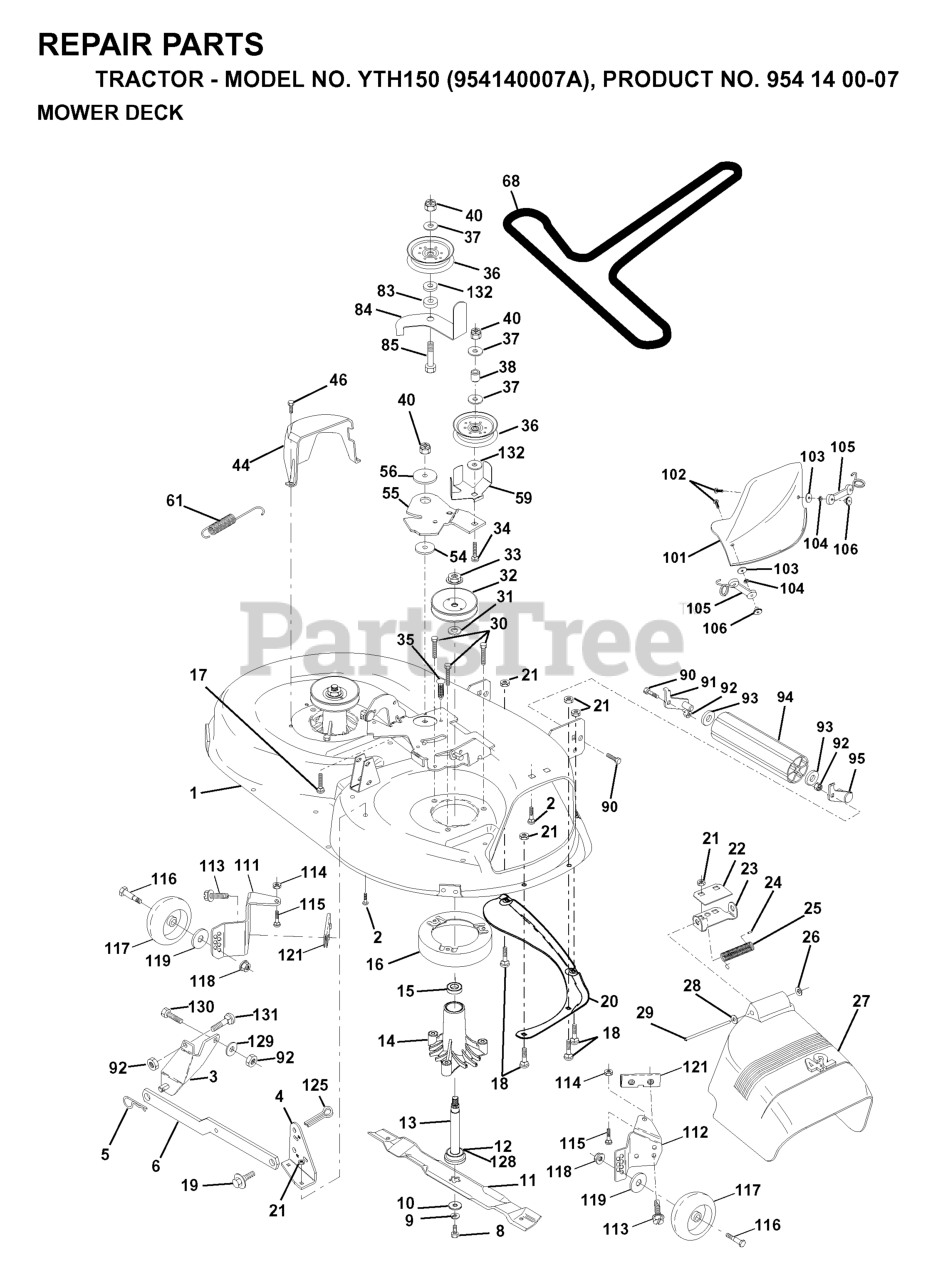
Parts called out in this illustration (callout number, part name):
1	DECK 42"
2	RP BOLT 5/16-18 X3/4 ZN/YEL GR
3	BRKT ASM SWAY BAR
4	BRKT DECK SW BAR
5	RETAINER-SPRNG RB
6	REAR SUSP ARM
8	BLADE BOLT
9	LOCKWASHER
10	WASHER.BLADE
11	BLADE.42".MULCH
12	BEARING.BALL.#6204.(MANDREL)
13	SHAFT ASM VENT
14	HOUSING.MANDREL.VENTED (MACHD)
16	STRIPPER
17	BOLT CARRIAGE
18	BOLT
19	BOLT SHD 5/16-18
20	BAFFLE
21	LOCKNUT
22	STIFFENER BRACKET
23	DEFLECTOR BRACKET
24	CAP-SLEEVE LT
25	SPRING TORSION
26	NUT PUSH M
27	SHIELD.DEFLECTOR.MOWER.42".BLK
28	Washer 11/32 x 5/8 x 16 Ga SD
29	ROD.HINGE
30	SCREW
31	WASHER
32	PULLEY/MANDREL
33	NUT
35	FASTENER.XMAS.TREE
36	FLAT IDLER PULLEY
37	WASHER
38	IDLER SPRING SPACER
44	GUARD MANDREL LH BLACK
46	SCREW.1/4-20X5/8
54	HARDENED WASHER
55	IDLER ARM
56	SPACER RETAINER
59	GUARD, BELT
61	SPRING EXTENSION
68	V-BELT TRIPATH
84	KEEPER.BELT.IDLER
85	BOLT
90	BOLT
91	BRACKET LH (A)
92	NUT
93	Washer 1 17/32 X 7/8 X 16 Ga
94	NOSE ROLLER
95	BRACKET RH (B)
101	COVER MULCH 42"
102	SCREW
104	LOCKWASHER #10
105	LATCH ASSEMBLY
106	WELDNUT
111	BRACKET WHEEL GAUGE LH 42" DK
112	BRACKET WHEEL GAUGE RH 42" DK
113	SCREW.THDROL.5/16-18X3/4.TTY
114	NUT
115	BOLT.CARR.5/16-18X1/2
116	BOLT, SHOULDER
117	WHEEL GAGE DONUT
118	LOCKNUT
119	WASHER.5/16.FLAT.STE.STD.
121	BRACKET.EXTRUDED.GAGE.WHEEL
125	Pin Cotter 1/4 x 1 Plated
128	WASHER FELT
129	WASHER
131	BOLT D
132	Washer 13/32 x 1-3/8 x 13 Ga.
